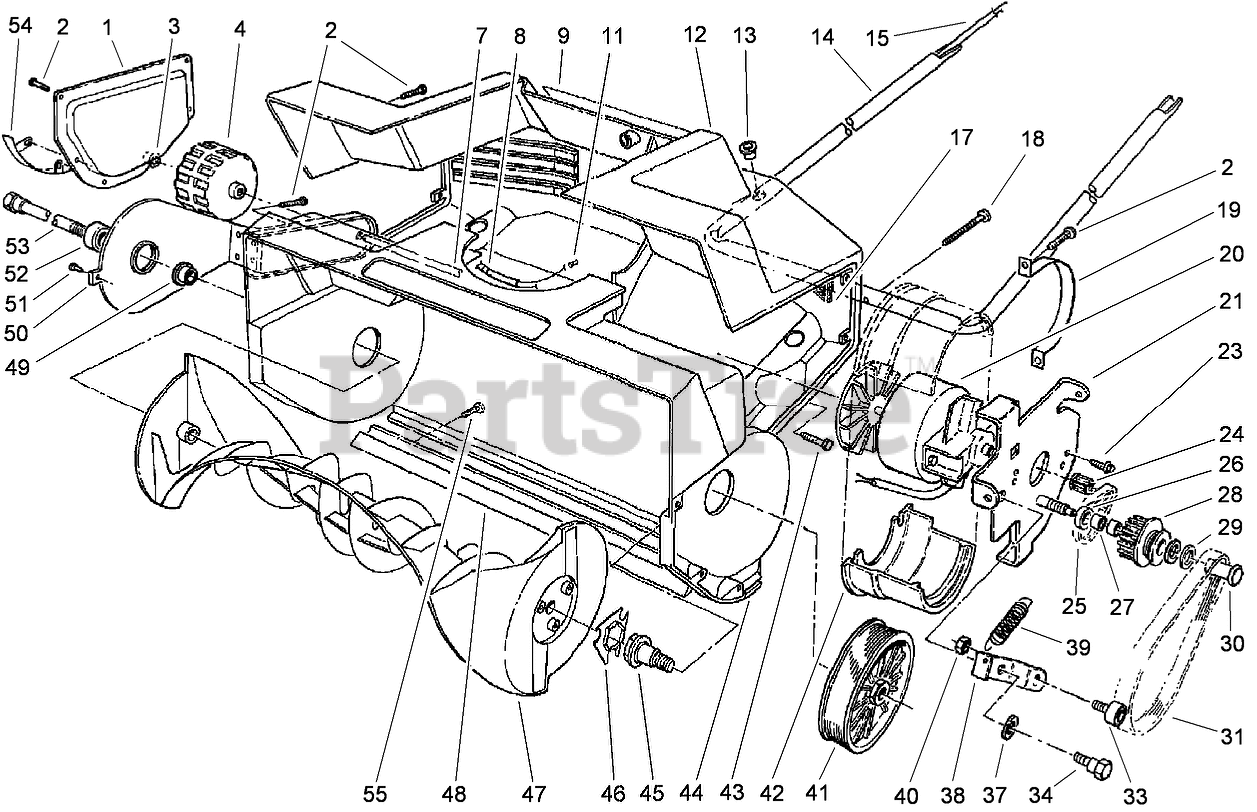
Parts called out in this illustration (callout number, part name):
1	Plate-Side
2	SCREW-PPH
3	PUSHNUT-CAP, WASHER
4	Wheel
7	Shaft-Axle
8	Relief-Strain
9	Decal-Danger
11	Connector
12	Shroud-Housing
13	BUSHING
14	Tube-Lower Handle
15	Wire Harness
17	Filter-Foam
18	Screw-Pan Head
19	Strap-Motor
20	Motor
21	Motor Plate ASM
23	Screw-Hex Washer Hd.
24	Pulley-Driver
25	BELT-PULLEY, IDLER/DRIVER
26	WASHER
27	Bearing-Needle
28	Idler Pulley ASM (Incl. Ref. #27)
29	WASHER-THRUST
30	Bolt-Idler
31	Belt-Drive
33	Bearing ASM (Incl. Ref. #40)
34	SCREW-SHOULDER
37	WASHER
38	Bracket-Idler
39	Spring
40	NUT-LOCK, NI
41	Pulley-Driven
42	Clamp-Motor Bracket
43	SCREW-HH
44	Housing-Rotor
45	Shaft-Driver, Rotor
46	Coupler-Rotor
47	Rotor
48	Scraper
49	BUSHING
50	Wheel Bracket ASM (Incl. Ref. #52)
51	RIVET-POP
52	Bearing-Ball
53	Shaft-Rotor
54	Skid-Housing
55	Screw-Pan Head
